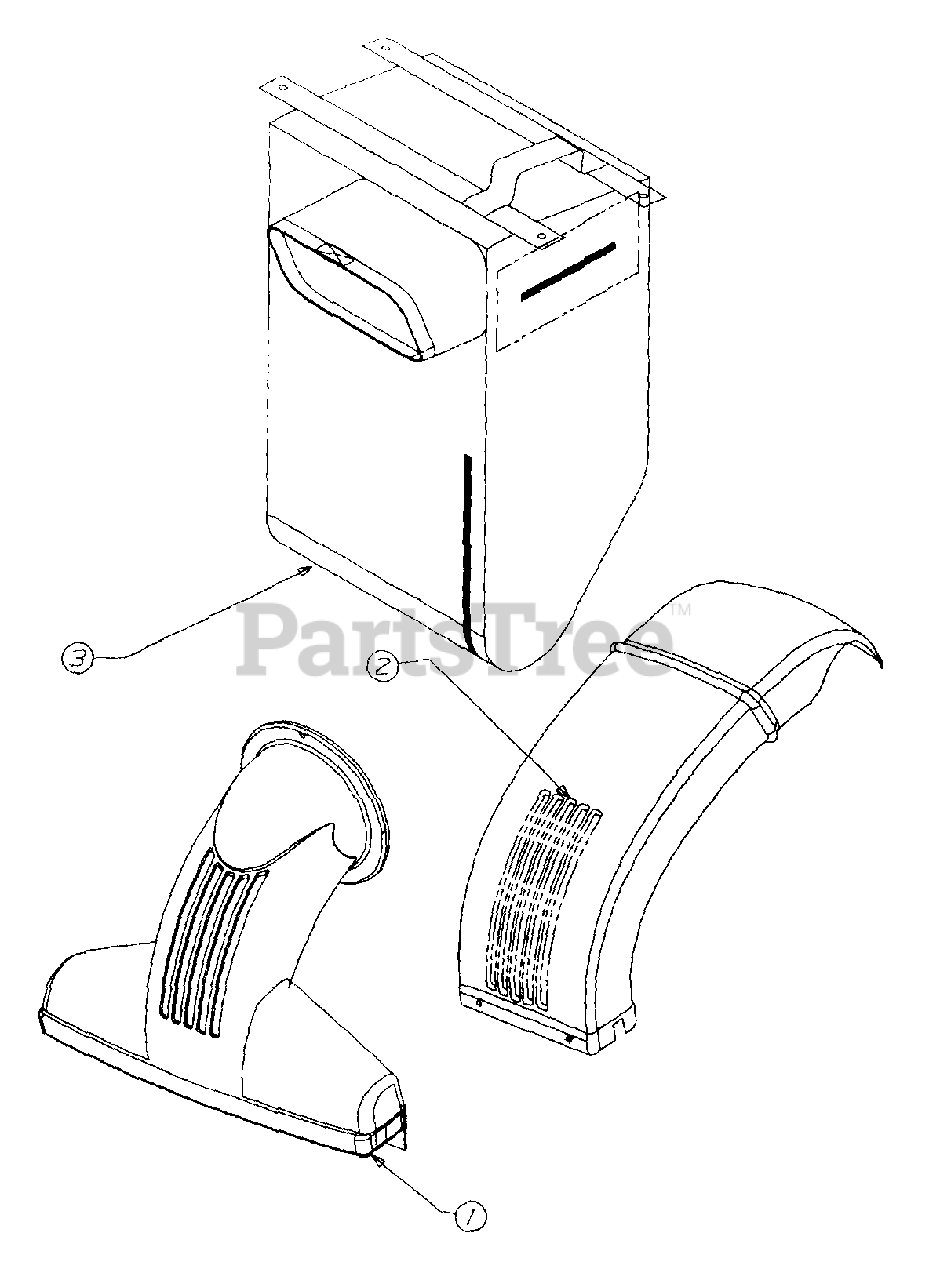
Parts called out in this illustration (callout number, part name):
1	NOZZLE ASS'Y. - VACUUM
2	CHUTE - DISCHARGE
3	BAG - VACUUM
